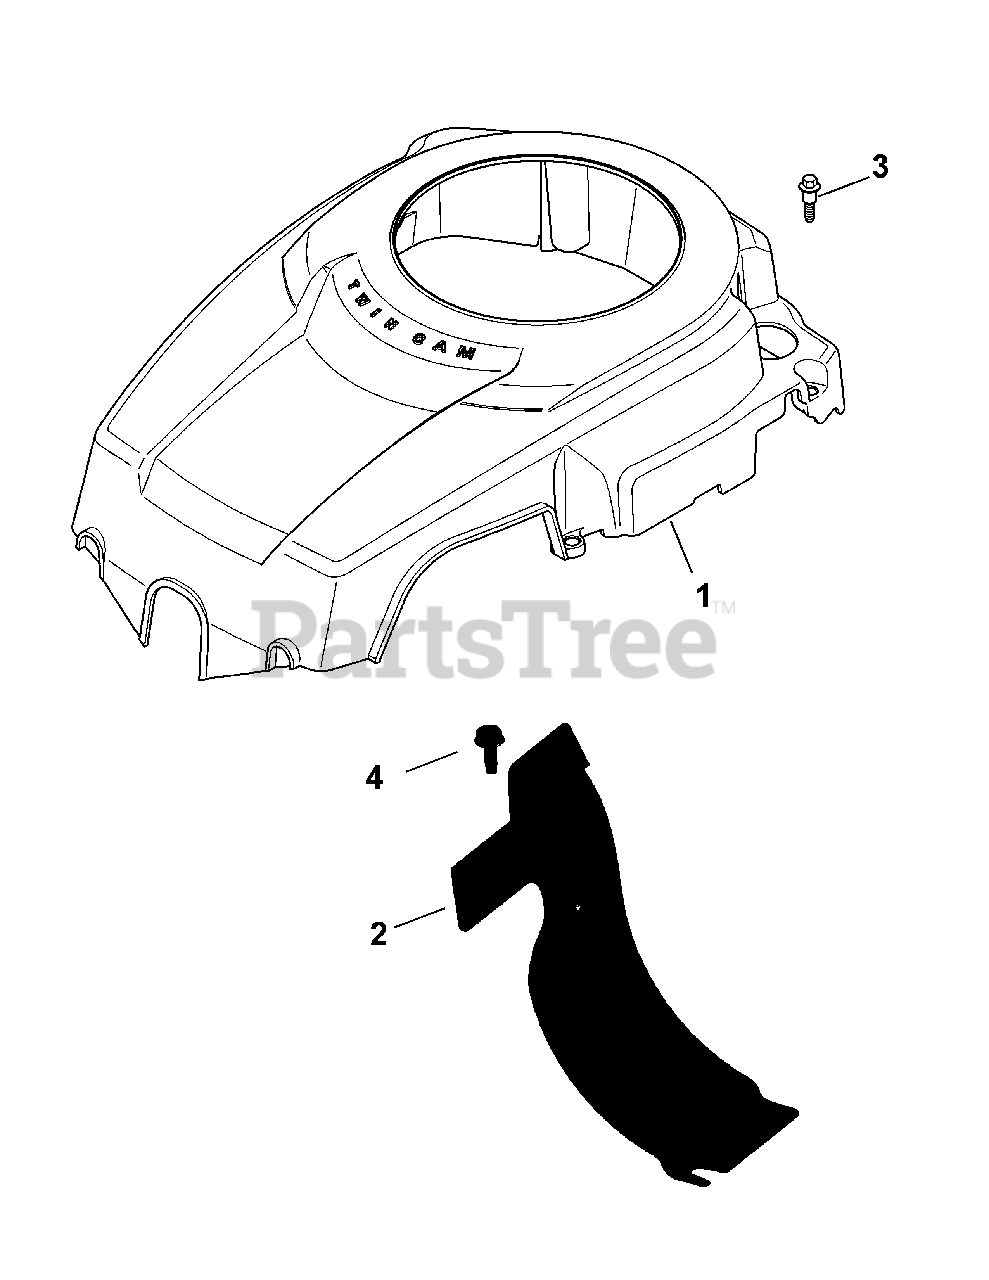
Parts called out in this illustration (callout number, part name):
1	Blower Housing Kit
2	Barrel Baffle
3	Shd. Thd. Frm. Screw, M6 X 1 X 26
4	Flg. Thd. Frm. Screw, M6 X 1.0 X 16
